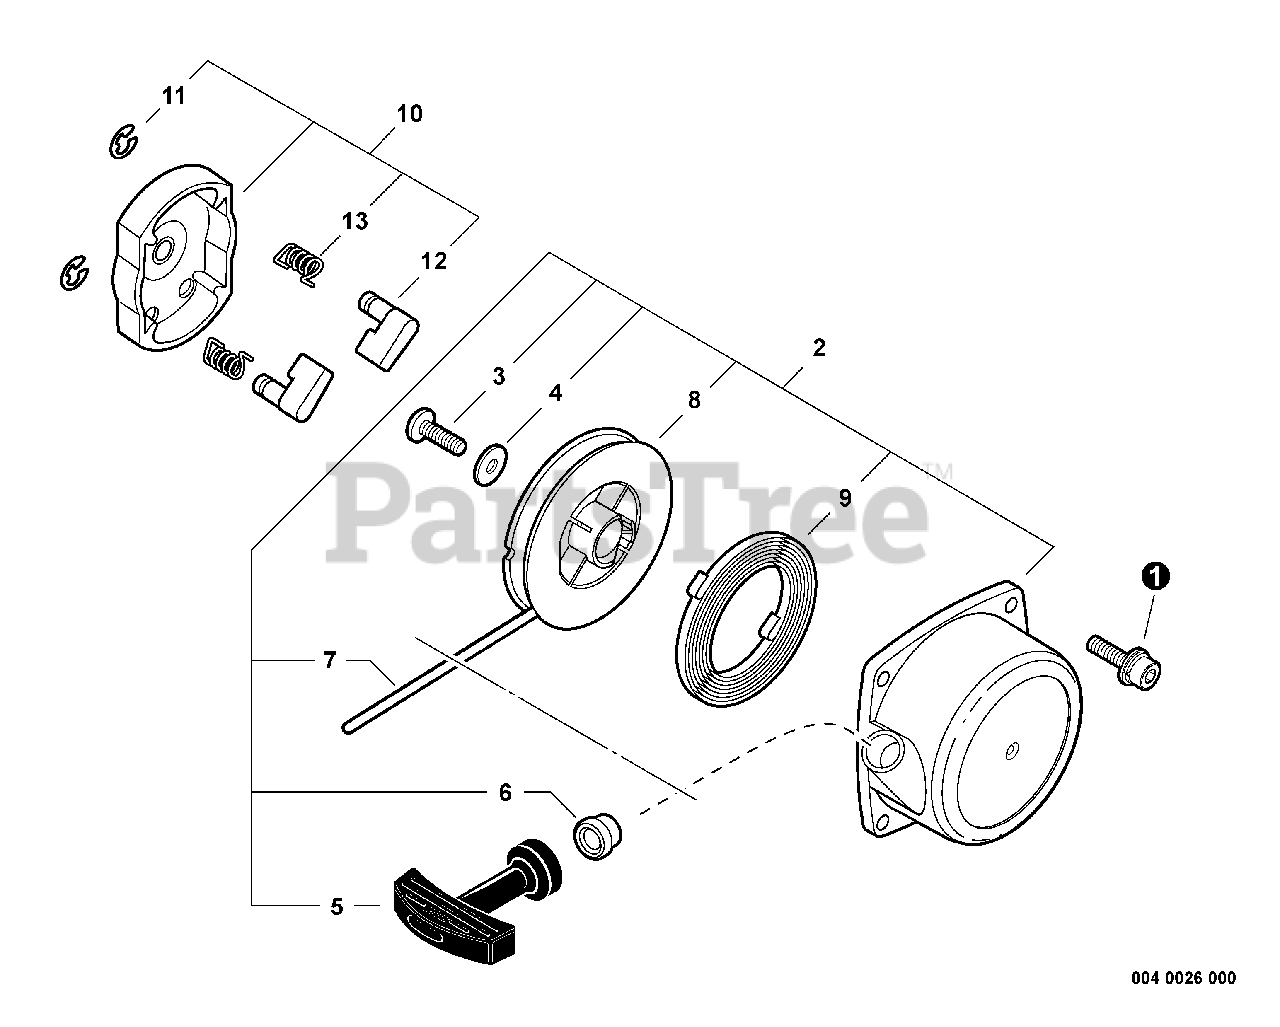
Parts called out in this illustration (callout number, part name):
1	BOLT 4×18
2	STARTER, RECOIL
4	WASHER
5	GRIP, STARTER
6	GUIDE, ROPE
7	ROPE, STARTER 3.8×1400
8	REEL, ROPE
9	SPRING, RECOIL
10	PAWL ASSY, STARTER
11	E-RING 4
12	PAWL, STARTER
13	SPRING, RETURN
